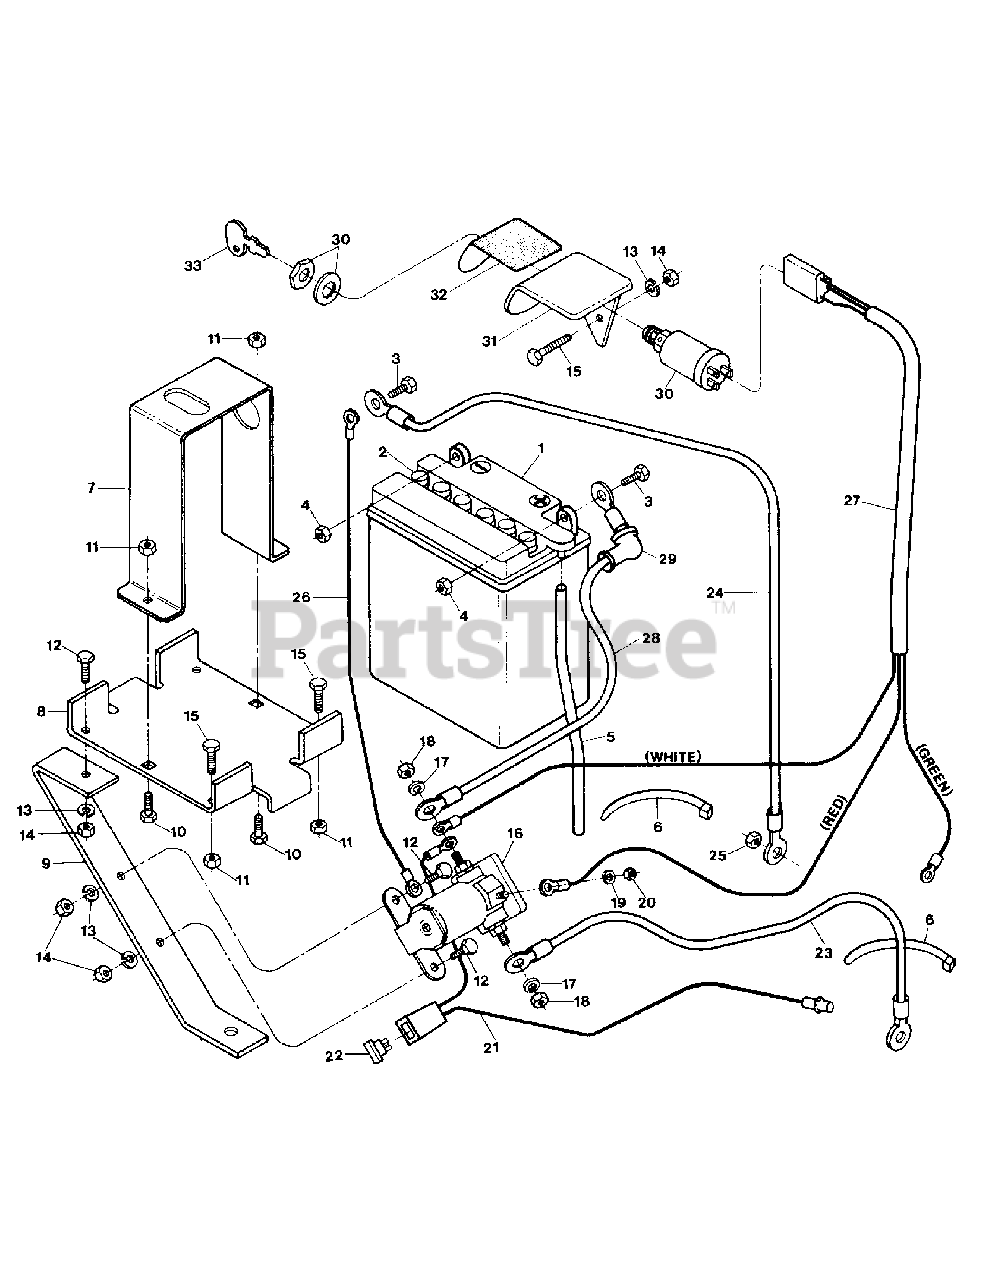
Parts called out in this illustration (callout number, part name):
1	BATTERY
2	CAP-YELLOW
3	SCREW HHS 1/4-20 X .
4	NUT, HEX
5	TUBE-VENT BATTERY/HSE
6	TIE-RED
7	CLAMP-BATTERY PNT
8	BRKT-BATT BASE PNT
9	SUPT-BATT BRKT PNT
10	SCR-HHCS 1/4-20X1 GR5
11	NUT-H/LK 1/4-20
12	SCR-HHCS 1/4-20X5/8 GR5
13	WASHER-LK .25 ZP
14	NUT-HEX 1/4-20 ZP
15	SCR-HHCS 1/4-20X1.250 GR 5
16	KIT-SOL W/HDW (INCL. 17-20)
17	WASHER-LK .312
18	NUT-HEX 5/16-24
19	WASHER-LK M10
20	NUT-HEX 3/16-32
21	ASSM-WIRE (INCL. 22)
22	FUSE-5AMP ELEC START
23	CABLE-STARTER MOTOR TO SOLENOID
24	CABLE (-) BATTERY POST TO ENGINE
25	NUT-HEX 5/16-18
26	WIRE ASSEMBLY, NEGATIVE BATTERY POST TO SUPPORT BRACKET
27	WIRE HARNESS, INCL. RECEPTACLE & THREE WIRES
28	CABLE-POSITIVE BATTERY POST TO SOLENOID ( USE WITH REF. NO. 29)
30	KEYSWITCH W/KEYS
31	BRKT-KEYSWITCH W/DECAL (INCL. 32)
32	DECAL-IGNITION
33	KEYS(1 PAIR) FOR SWITCH
